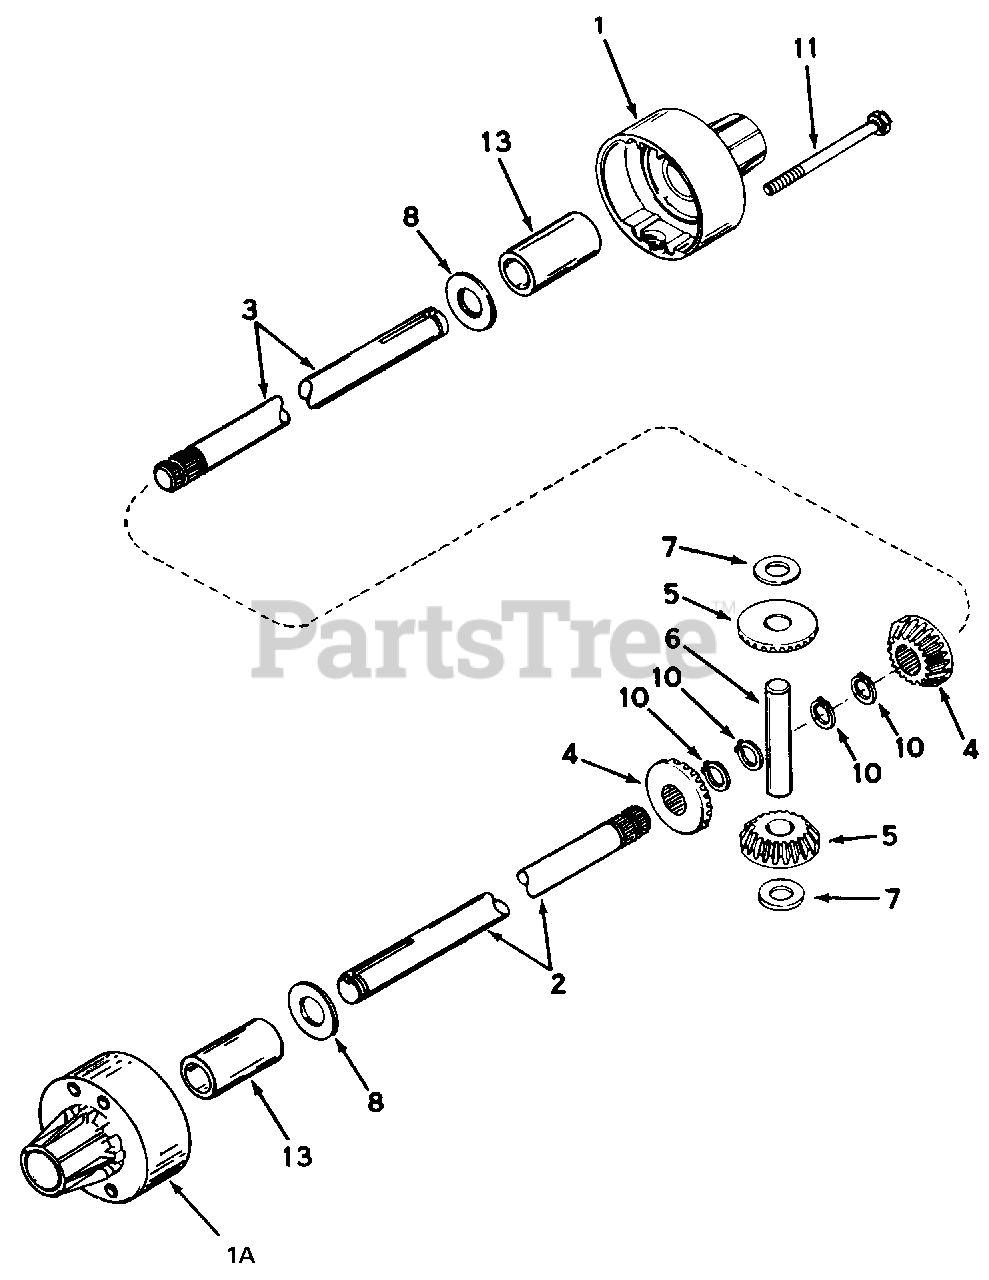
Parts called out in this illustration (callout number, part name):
1	HOUSING, Differential Carrier (Incl. Ref. No. 13)
1A	HOUSING, Differential Carrier (Incl. Ref. No. 13)
2	AXLE (8-19/32" Long)
3	AXLE (16-29/32" Long)
4	GEAR, Bevel
5	GEAR, Bevel
6	PIN, Drive
7	WASHER, Thrust
10	RING, Retaining (Pkg. of 2)
11	SCREW, Flanged Hex Hd., 5/16-18 x 3-15/16
